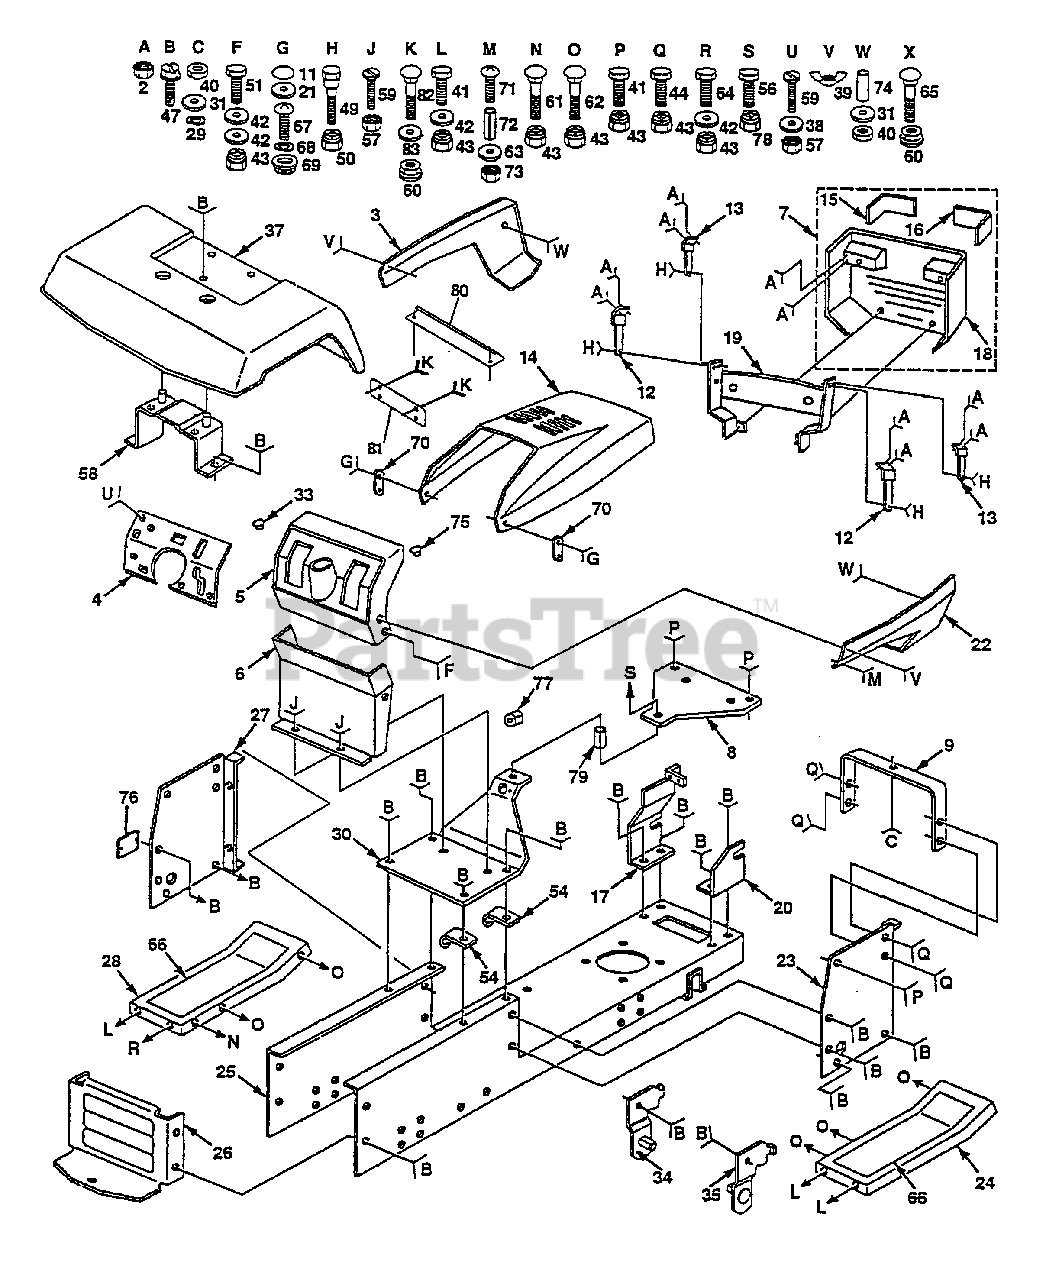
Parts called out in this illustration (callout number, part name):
2	Nut, Hex, Keps 1/4-20 UNC
3	Side Panel, LH
4	Plate, Dash
6	Dash, Lower
7	Grill Assembly
8	Plate, Battery Support
9	Support, Dash
11	Cap, Black
12	Strap Assembly, Hinge, Rear
13	Strap Assembly, Hinge, Front
15	Lens, Headlight, LH, Smoked
16	Lens, Headlight, RH, Smoked
17	Pivot Bracket Assembly, LH
18	Grille
19	Support Assembly, Grille
20	Pivot Bracket Assembly, RH
21	Washer, Cap
22	Side Panel, RH
23	Dash Panel, RH
24	Footrest, RH
25	Chassis 11 ga
26	Drawbar
27	Dash Panel, LH
28	Footrest, LH
29	Washer, Lock,Hvy Helical 1/4
31	Washer 9/32 x 3/4 x 16 Gauge
33	Plug, Button
34	Pivot Bracket Assembly, Rear, LH
35	Pivot Bracket Assembly, Rear, RH
36	Plug, Dome, Black
37	Fender
38	Washer 11/32 x 11/16 x 16 Gauge
39	Wing Nut, Plastic 1/4-20
40	Nut, Hex, Fin. 1/4-20 UNC
41	Bolt, Hex, Fin. 3/8-16 UNC x 3/4
42	Washer 13/32 x 13/16 x 12 Gauge
43	Nut, Crownlock 3/8-16 UNC
44	Bolt, Hex, Fin. 3/8-16 UNC x 1
45	Strip, Foam
47	Screw, Thd., Roll. 3/8-16 x 3/4
49	Bolt, Shoulder 1/4-20 UNC
50	Nut, Crownlock 1/4-20 UNC
51	Bolt, Hex, Fin. 3/8-16 UNC x 1-1/4
54	Clip, Fuel Line
56	Bolt, Hex, Fin. 5/16-18 UNC x 2
57	Nut, Hex, Keps 5/16-18 UNC
58	Bracket Fender
59	Screw, Machine 5/16-18 UNC x 3/4
61	Bolt, Carriage 3/8-16 UNC x 1
62	Bolt, Carriage 3/8-16 x 3/4
63	Washer 7/32 x 1/2 x 18 Gauge
64	Bolt, Hex, Fin. 3/8-16 UNC x 7/8
66	Pad, Footrest
67	Screw, Machine, Cross Pan Head #10-24 x 1/2
68	Washer, Lock #10
69	Nut, Weld
70	Latch, Chute
71	Screw, Machine, Cross Pan Head #10-24 x 1-1/4
72	Spacer, Split #10 x 3/4
73	Nut, Hex, Keps #10-24 UNC
74	Spacer 17/64 x 1/2 x 3/8
76	Cover Access
77	Bushing Snap Split
78	Nut Lock 5/16-18
79	Spacer Split
80	Spacer Fender LT
81	Plate Extention Fender
82	Bolt rdhd sqnk 3/8-16 x 1 Gr5
83	Washer 17/32 x 7/8 x 16Ga
